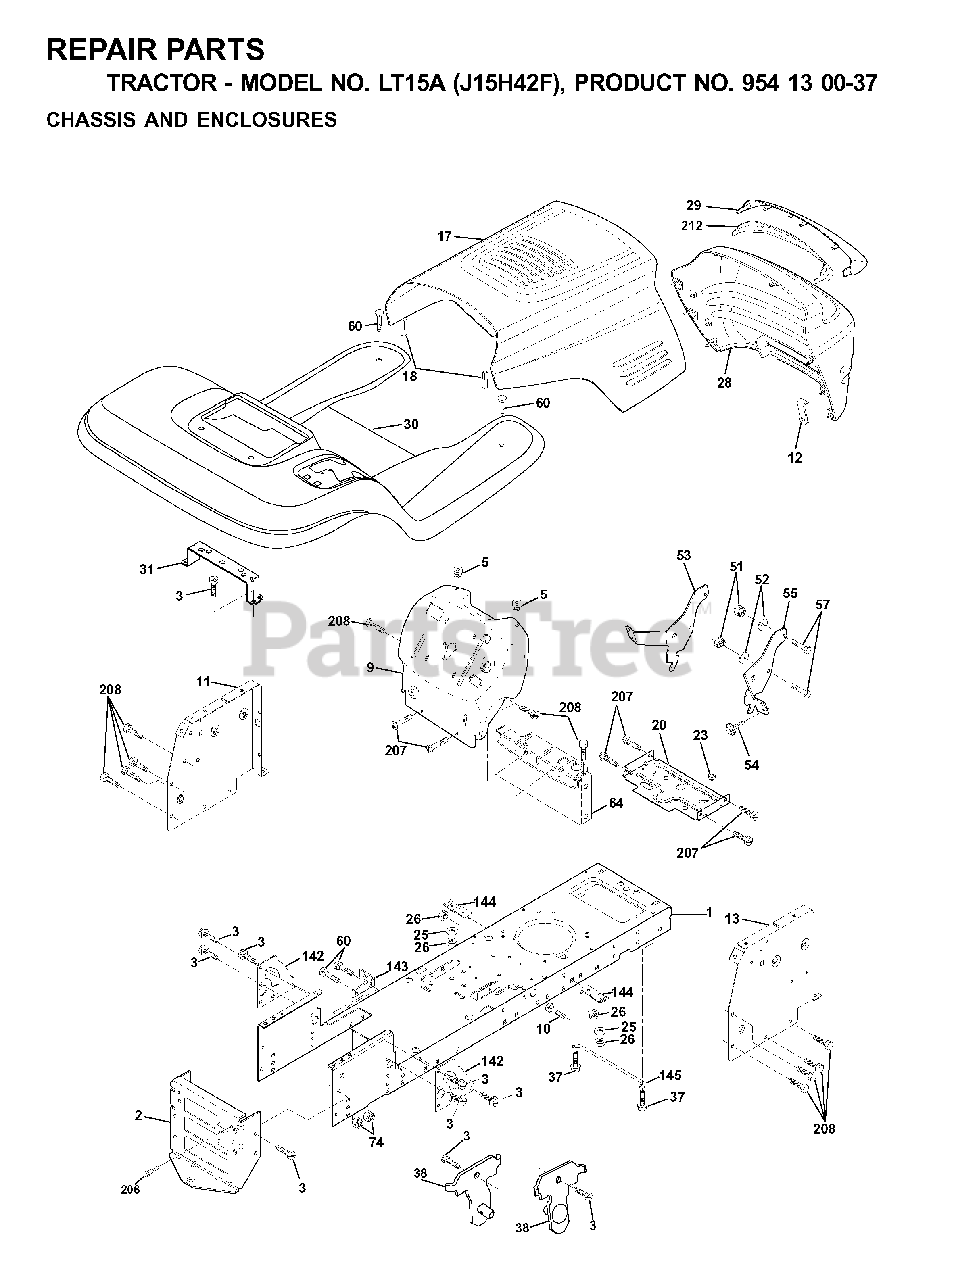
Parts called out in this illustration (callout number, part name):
2	DRAWBAR
3	SCREW 3/8-16X3/4
5	BUMPER.RUBBER.HOOD
10	BOLT D
11	PANEL DASH LH
13	PANEL DASH
18	BUMPER HOOD T
20	PLATE MTG
23	GROMMET T
25	WASHER
26	NUT
38	BRACKET
51	LOCKNUT
57	BOLT
64	DASH LOWER
74	LOCKNUT
140	BRACKET SUSPENSION FRONT
142	PLATE
143	BRACKET, SWAY BAR
144	BRACKET FOOTREST
145	ROD PIVOT CHASSIS/HOOD
206	SHOULDER BOLT 5/16-18TT
207	SCREW, 5/16-18 X 1/2
208	SCREW 3/8-16X1/2
